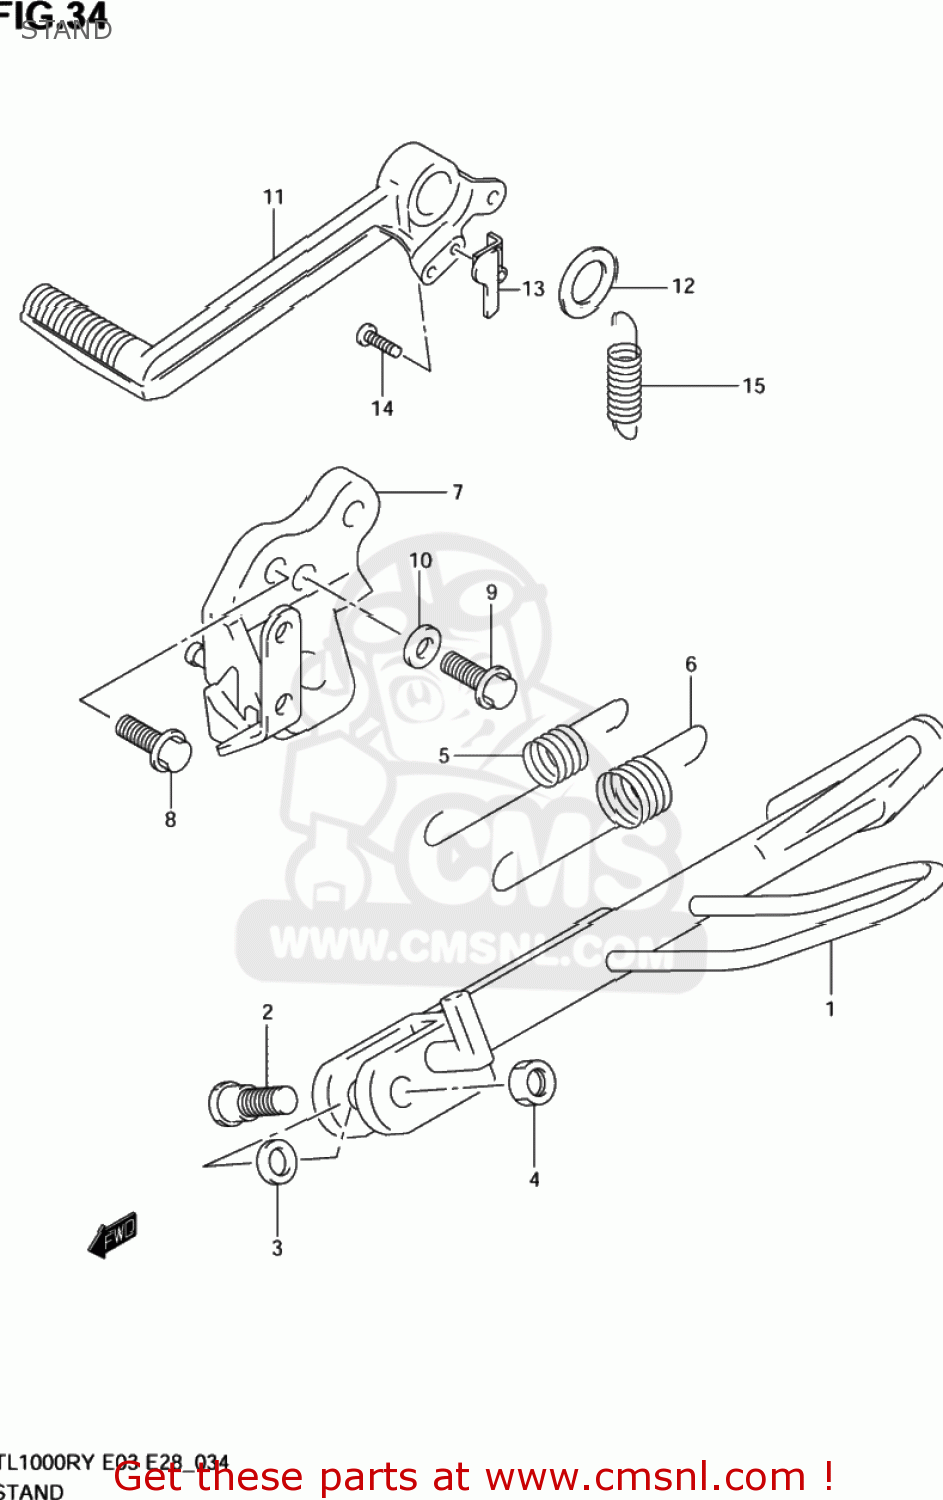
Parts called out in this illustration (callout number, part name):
1	STAND,PROP
2	BOLT(10X34)
3	SHIM
4	NUT
5	SPRING
6	SPRING
7	BRACKET,PROP STAND
8	BOLT
9	BOLT
10	WASHER
11	PEDAL,BRAKE
12	WASHER(18X24X1)
13	HOOK,RETURN SPRING
14	SCREW
15	SPRING
